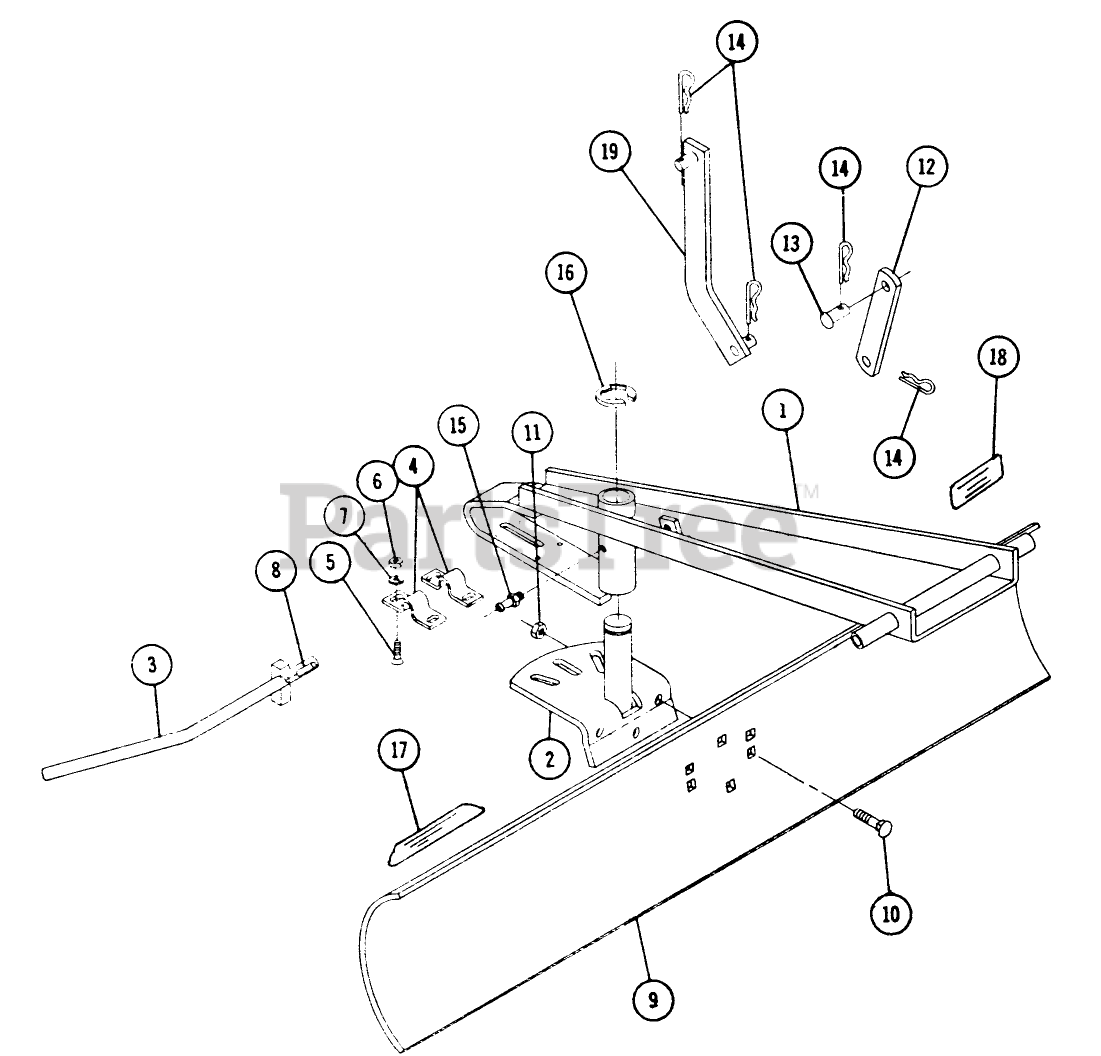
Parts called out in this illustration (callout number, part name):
1	Frame Assembly
2	Blade Support
3	Rod-Angle Adjustment
4	Bracket
5	Screw 1/4-20 x 5/8 Mach. Rd. Hd. Slotted
6	Nut, 1/4-20
7	Washer
8	Pin-Roll
9	Blade
10	Bolt 3/8-16 x 1
11	3/8-16 E.S.
12	Lift Link-Vertical Engine Shaft Tractor
14	Hairpin
15	Zerk
16	E RING
17	Decal
18	Decal Safety First
19	Ass-y. Lift Link
